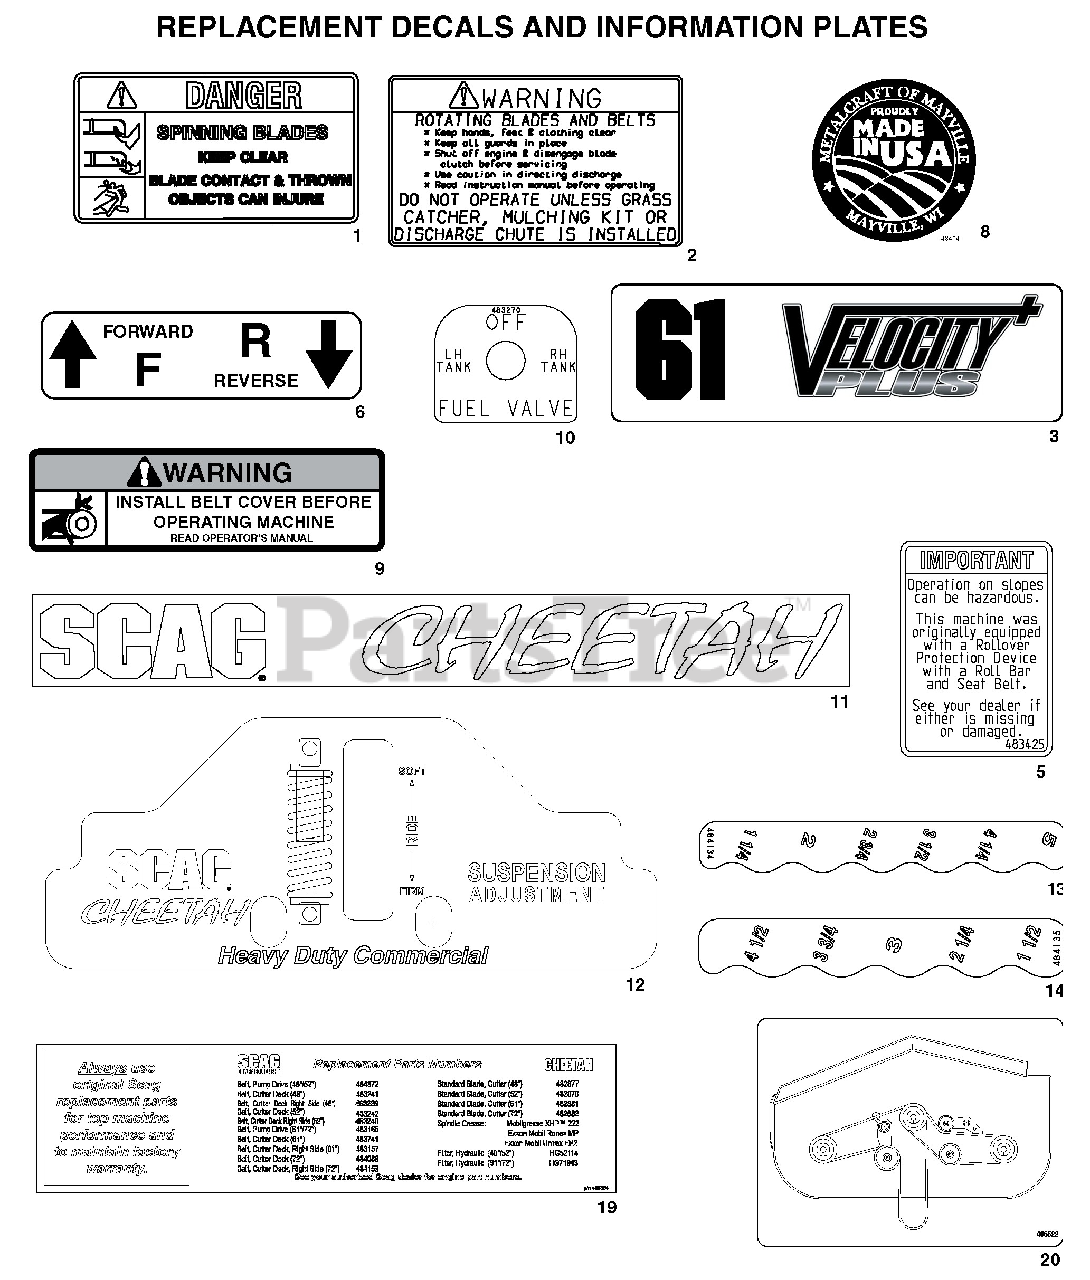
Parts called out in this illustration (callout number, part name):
1	Decal, Spinning Blades
2	Decal, Knives
3	Decal, 61" Velocity Plus
3	Decal, Velocity Plus - 61RD
3	Decal, 72" Velocity Plus
5	Decal, ROPS
6	Decal, Traction Control
8	Decal, Made in USA
9	Decal, Belt Cover
10	Decal, Fuel Shut Off
11	Decal, Scag Cheetah
12	Decal, Suspension Adjustment
13	Decal, Deck Height - LH
14	Decal, Deck Height - RH
19	Decal, SCZ Replacement Parts
20	Decal, SCZ Belt Routing
